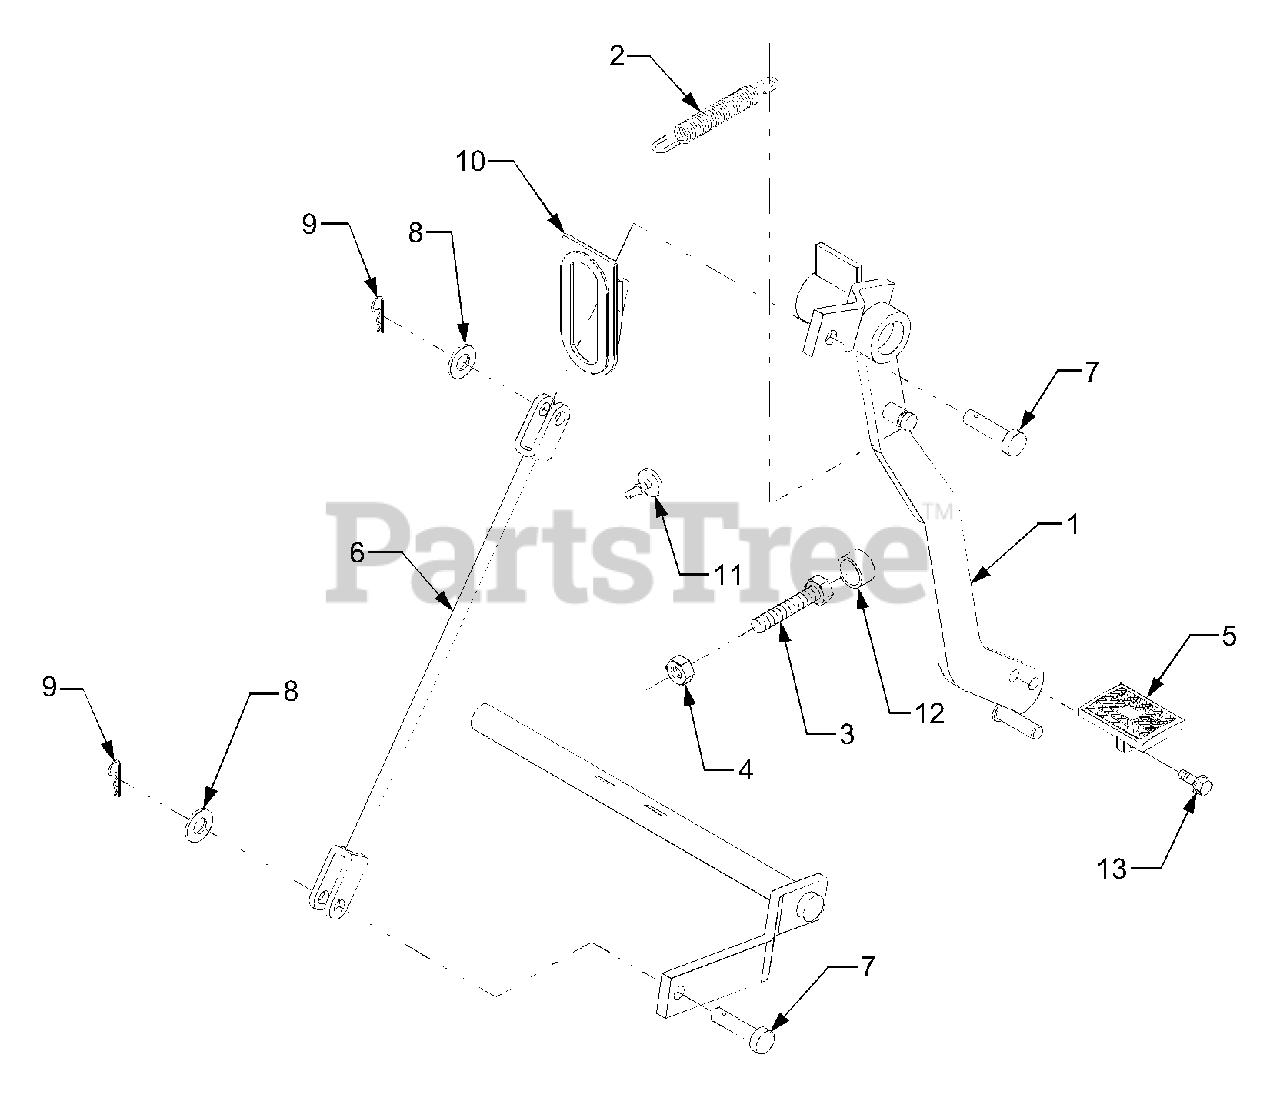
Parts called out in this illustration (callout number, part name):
1	Pedal, Clutch
2	Spring, Clutch Lock
8	Washer, Plain
11	Cushion, Pedal
